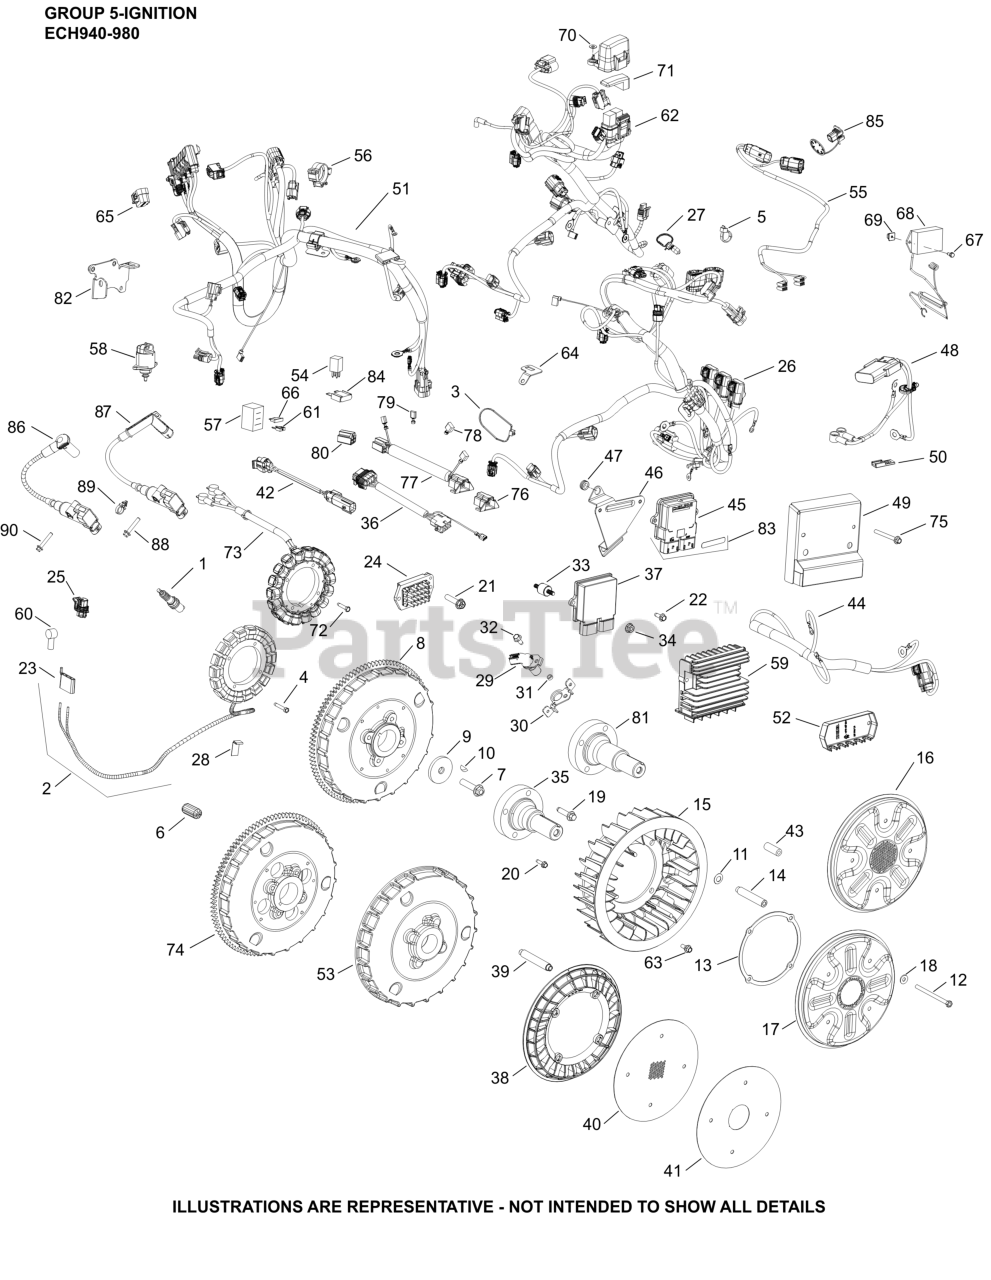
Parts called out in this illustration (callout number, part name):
1	PLUG, SPARK
2	KIT, 25 AMP STATOR ASSY.
3	TIE, CABLE
4	SCREW, THREAD FORMING
5	TIE, WIRE
6	SLEEVE, EMI SUPPRESSION
8	FLYWHEEL ASSEMBLY
9	WASHER, FLAT 13/32"
10	KEY, 3/16" X 5/8"
11	WASHER, SPRING 10 MM
12	SCREW, HEX HEAD
13	RING, SUPPORT
14	SPACER, GRASS SCREEN
15	FAN-(#6215706S)
16	SCREEN, GRASS
18	WASHER, FLAT 1/4" (O.D. 5/8")
20	SCREW, THREAD FORMING
21	SCREW, HEX FLANGE HI-LO
22	SCREW, THREAD FORMING
23	CONNECTOR
24	REGULATOR, RECT (20-30AMP, FW W/OVP)
26	HARNESS, WIRING (8-BAY EFI HORIZONTAL)
27	TIE, WIRE
28	CLIP, BLOWER HOUSING
29	SENSOR, SPEED
30	BRACKET, CRANK SENSOR
32	SCREW, THREAD FORMING
33	ISOLATOR, VIBRATION STUD
34	NUT, FLG M5X.8
85	CAP, CONNECTOR (4-WAY, BLACK)
87	COIL, IGNITION - EFI (RFI/EMC)
90	SCREW, HEX FLANGE
NI	SCREW, HEX FLANGE
NI	MODULE, ECU ECH940
